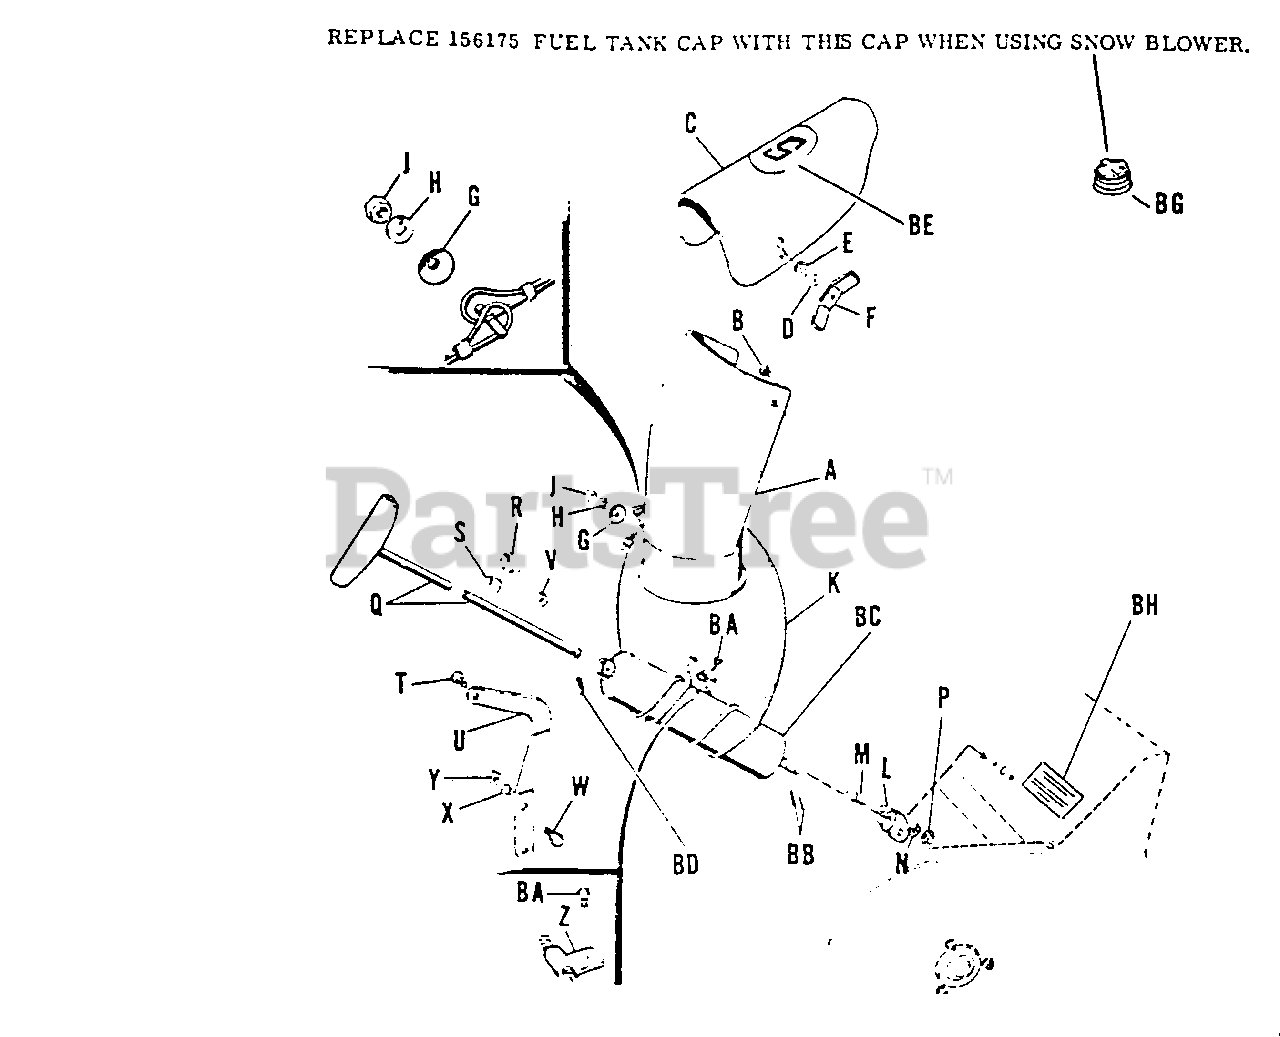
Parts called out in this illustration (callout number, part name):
A	Spout Assembly
B	Carriage Bolt, 5/16"-18 x 3/4"
C	Spout Extension
D	Plain Washer, 3/8"
E	Special Hex. Lock Washer, 3/8"
F	NUT, Wing, 5/16-18
G	Cup Washer
H	Lock Washer, 5/16"
J	Full Hex. Nut, 5/16"-18
K	Cable Assembly
M	Hex Capscrew, 1/4"-20 x 5/8"
N	Lock Washer, 1/4"
P	Full Hex. Nut, 1/4"-20
S	Guide Liner
T	Hex. Capscrew, 5/16"-18 x 1-1/4"
U	Rod Guide Support
V	Full Hex. Lock Nut, 5/16"-18
W	Hex. Capscrew, 3/8"-16 x 1-1/4"
X	Lockwasher, 3/8"
Y	Hex. Nut, 3/8"-16
Z	Clamp (For Service Only)
BA	Self-Tapping Screw, 1/4-20 x 3/8" lg.
BB	Cotter Pin, 3/32" x 5/8"
BC	Tube Assembly Spout Control
BD	Cotter Pin, 5/32" x 1"
BF	Set Screw, 1/4"-28 x 1/4" lg.
BG	Fuel Tank Cap
BH	Decal Safety
